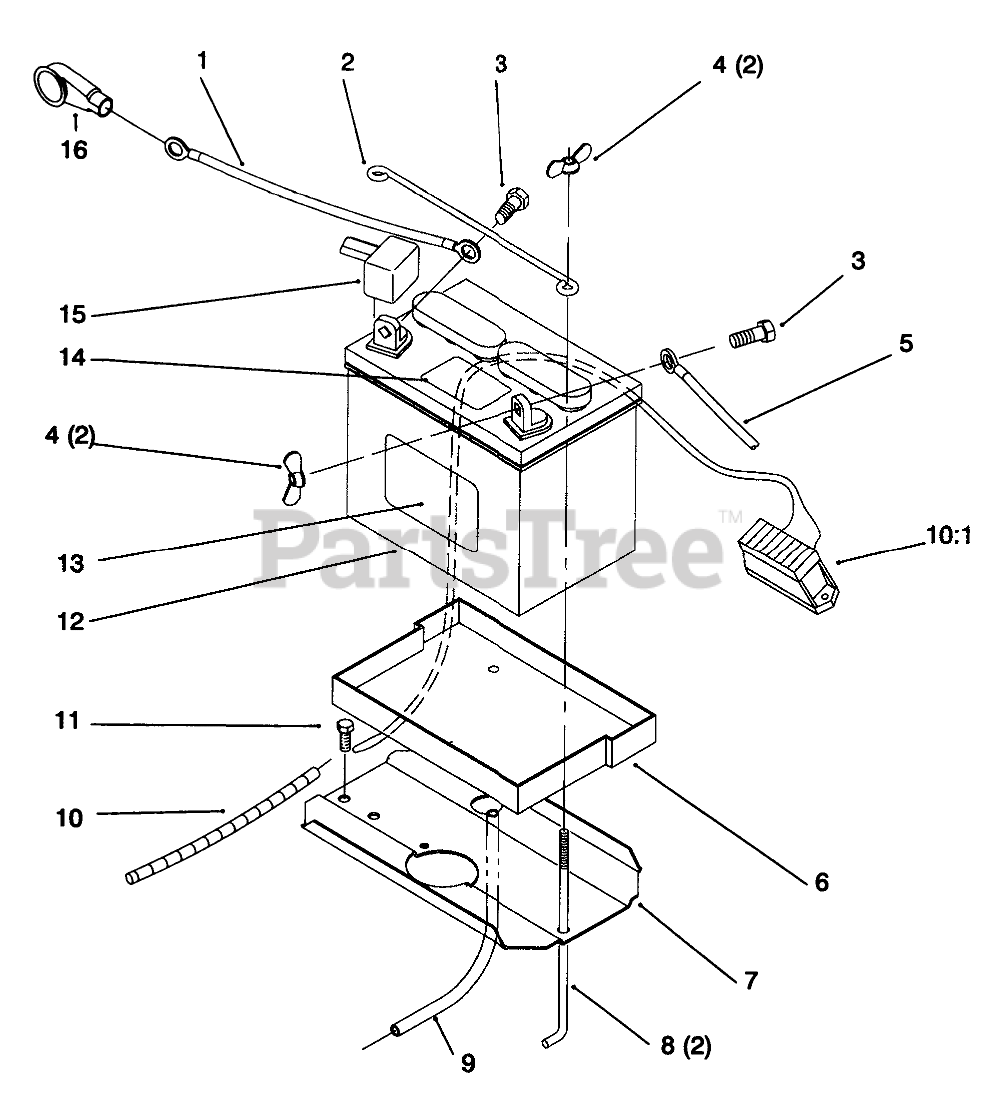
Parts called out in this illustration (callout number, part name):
1	WIRE -10" RED
2	ROD-BATTERY HOLD DWN
3	SCREW-HH
4	NUT-WING
5	WIRE -BLACK
6	TRAY-BATTERY
7	PLATE-BATTERY
9	TUBE-21" BATTERY DRAIN
10	HARNESS - WIRE 15H
11	SCREW-HWHTF
12	Battery
13	Decal-Battery Charge Ins (Only On: 72064)
14	Decal Danger (Only On: 72064)
15	Boot
